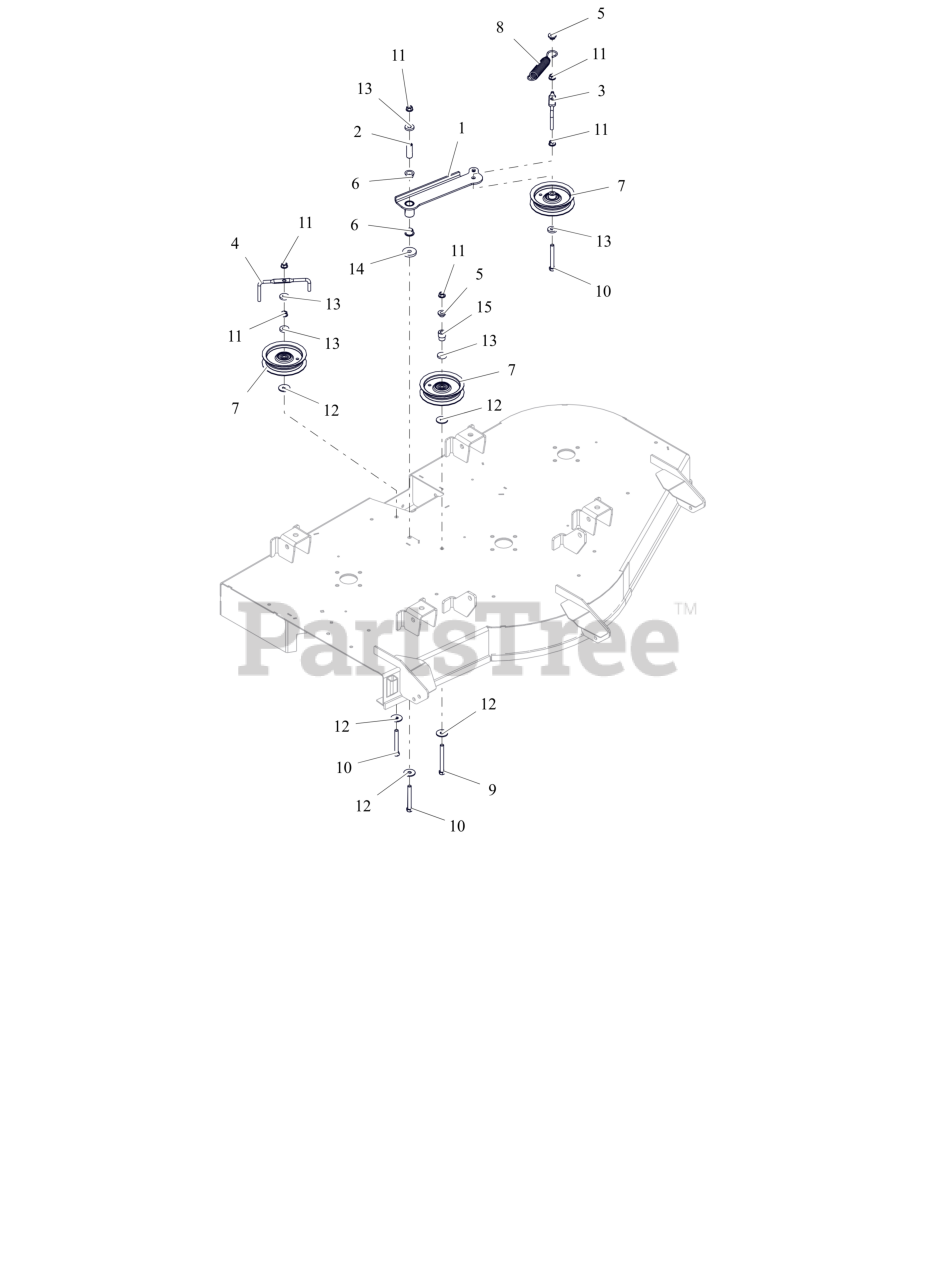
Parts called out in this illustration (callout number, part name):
1	WLDMT, IDLER ARM-52"
2	SPACER, .375IDX.625ODX1.66 PM
3	WIREFORM, BELT FINGER
4	BELT FINGER
5	BSHG-FLG .385X.500X.875X.406
6	BSHG-FLG, .625X.750X.500X1.00
7	IDLER, FLAT - 4.06" X .75"
8	SG-TENS .135X.98X6.0 WLD 62
9	BLT, HEX .38-16X3.50 G5 ZCC
10	BLT, HEX .38-16X3.00F G5 ZCC
11	NUT-LK-CTR-FLG .375-16 GF ZCC
12	WSHR FL STL .406X1.25X.10ZC120
13	WSHR, FLT .406X1.00X.188 ZCC
14	WSHR, FLT .406X1.50X.245 ZCC
15	BUSHING, IDLER (P/M)
